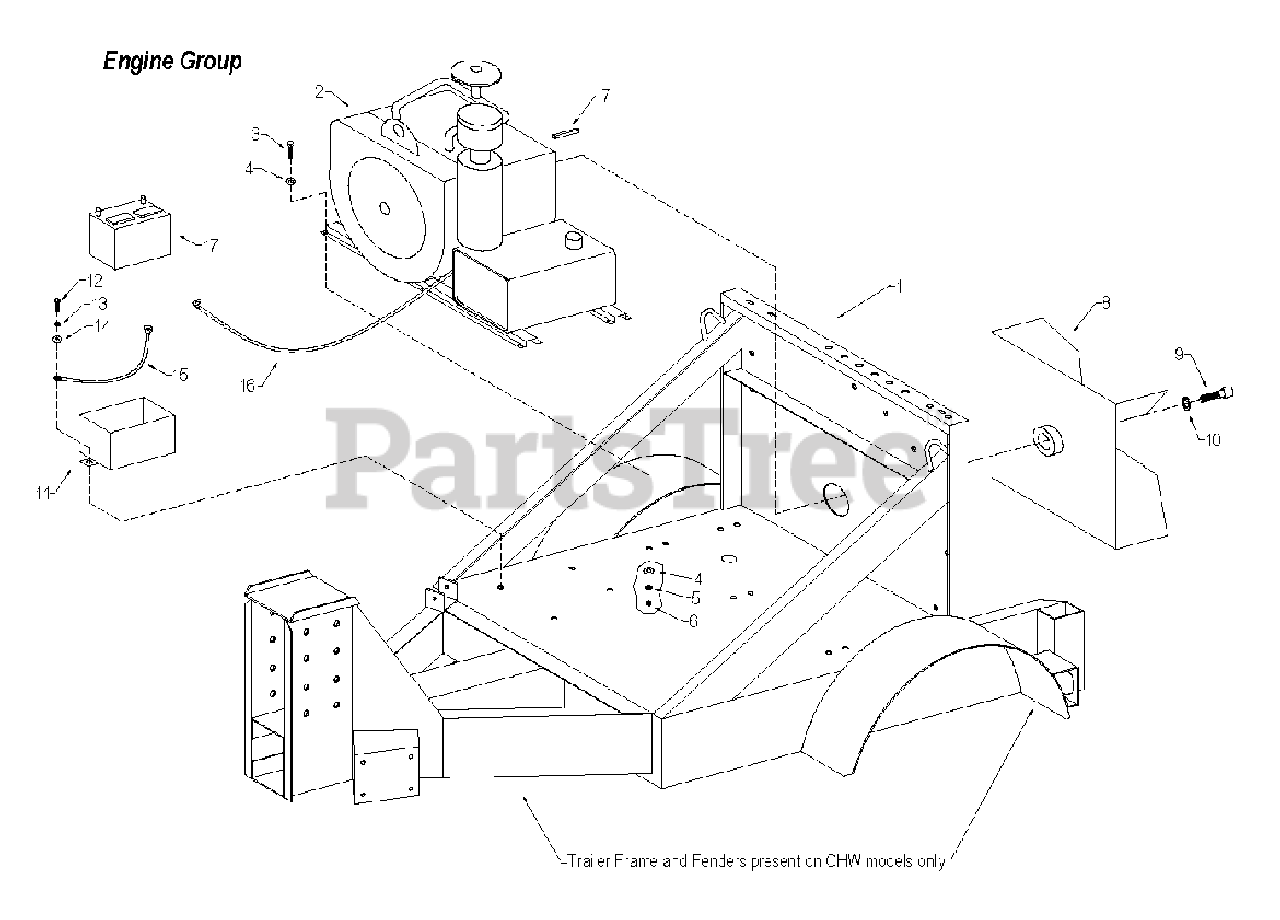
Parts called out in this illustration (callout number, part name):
1	Loader base – skid mount model
1	Loader base and trailer frame – CHW model
2	* 30 HP Wisconsin engine
3	3/8-16 x 1-1/4 hex bolt (engine mounting bolt)
4	3/8 flat washer
5	3/8 lock washer
6	3/8-16 hex nut
7	Impeller key
9-10	5/8-11 x 1-3/4 impeller bolt and lock washer group
11	Battery box
12	3/8 x 1-1/4 hex bolt (bolts battery box to base)
13	3/8 lock washer
14	3/8 flat washer
15	Battery cable, ground – 16S
16	Battery cable, positive – 42S
